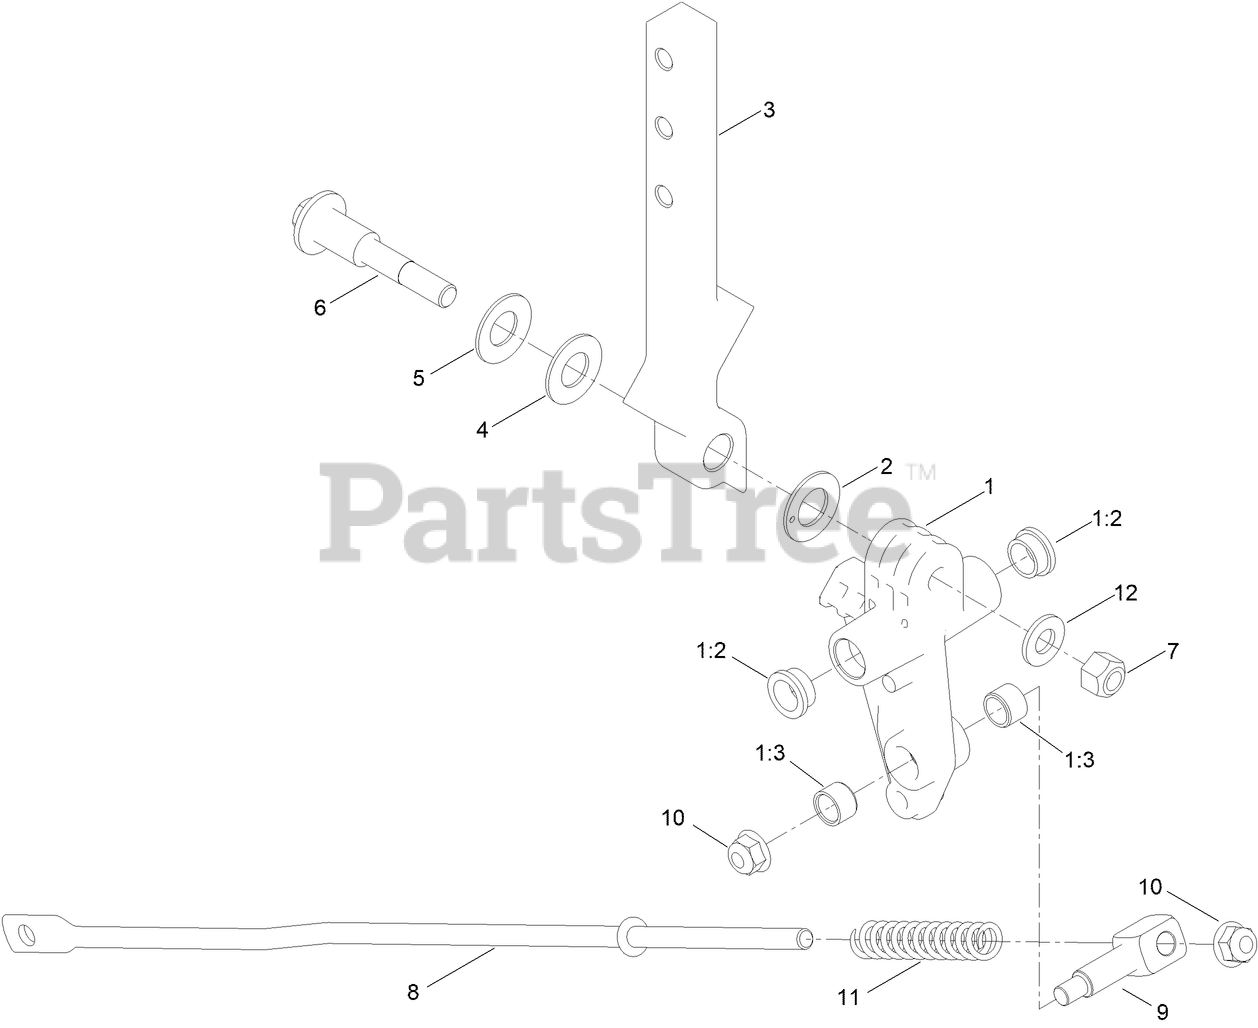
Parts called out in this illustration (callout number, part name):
1	CONTROL ARM ASM
1:2	BUSHING
1:3	BUSHING-SLEEVE
2	WASHER-FRICTION
3	ARM-CONTROL
4	WASHER
5	WASHER-BELLEVILLE
6	BOLT-PIVOT
7	NUT-LOCK, CONE
8	LINK-CONTROL
9	SWIVEL
10	NUT-HF, NI
11	SPRING-RETURN, NEUTRAL
12	WASHER-FLAT
